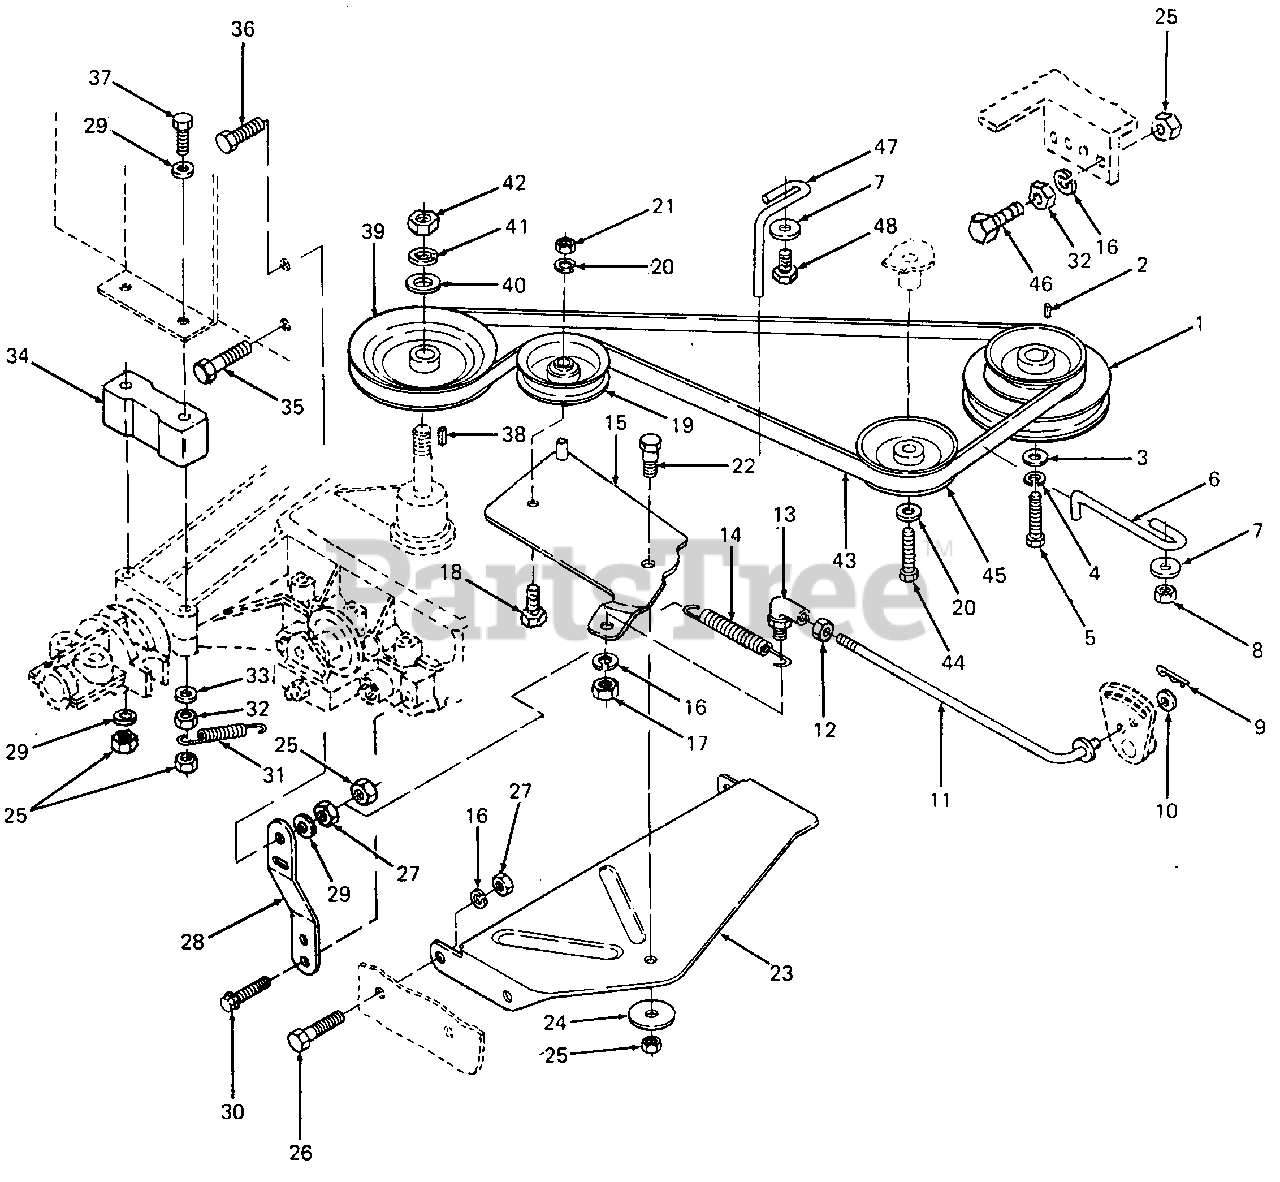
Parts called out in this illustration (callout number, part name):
1	Pulley, Engine
2	Key, Square, 1/4 X 2.0 Lg
3	Washer, Flat, .450 X 1.25 X .172 Thk HDN
4	Washer, Lock, 7/16
5	Screw, Hex Cap, M10 X 1.5 X 25 mm Lg
6	Guard, Belt
7	Washer, Flat, .344 X 1.125 X .12 Thk
8	Screw, Hex Cap, M8 X 1.25 X 35 mm Lg
9	Pin, Internal Cotter
10	Washer, Flat, .34 X .68 X .062 Thk
11	Rod, Idler Clutch
12	Nut, Hex Jam, 5/16-24 GR5
13	Ball Joint, 5/16-24
14	Spring, Extension
17	Nut, Hex, 5/16-24 GR5
18	Screw, Hex Cap, 3/8-16 X 2.25 Lg GR5
19	Idler, Flat
20	Washer, Lock, 3/8
21	Nut, Hex, 3/8-16 GR5
22	Screw, Shoulder, .437 Dia X .180
23	Bracket, Clutch Mounting
24	Washer, Flat, .344 X 1.12 X .063 Thk
25	Nut, Hex Center Lock, 5/16-18 GR5
26	Screw, Hex Cap, 5/16-18 X .62 Lg
27	Nut, Hex, 5/16-18 GR5
28	Brace, Transaxle
29	Washer, Bell, .345 X .88 X .06 Thk
30	Screw, Hex Washer Hd Tapp, 5/16-18 X .75 Lg
31	Spring, Extension
32	Nut, Hex Jam, 5/16-18 GR5
33	Washer, Flat, .344 X .875 X .06 Thk
34	Spacer, Axle
35	Screw, Hex Cap, 5/16-18 X .75 Lg GR5
36	Screw, Hex Cap, 5/16-18 X 1.0 Lg GR5
37	Screw, Hex Cap, 5/16-18 X 3.75 Lg GR5
38	Key, #4 Hi-Pro, 3/32 X 5/8 Dia HDN
39	Pulley, 8.0 Dia
40	Washer, Flat, .531 X 1.00 X .027 Thk
41	Washer, Lock, 1/2
42	Nut, Hex Jam, 1/2-20
43	V-Belt, 4L X 90" Lg
44	Screw, Hex Cap, 3/8-16 X 1.25 Lg GR5
46	Screw, Shoulder
47	Guide, Belt
48	Screw, Hex Cap, 5/16-18 X 1.25 Lg GR5
